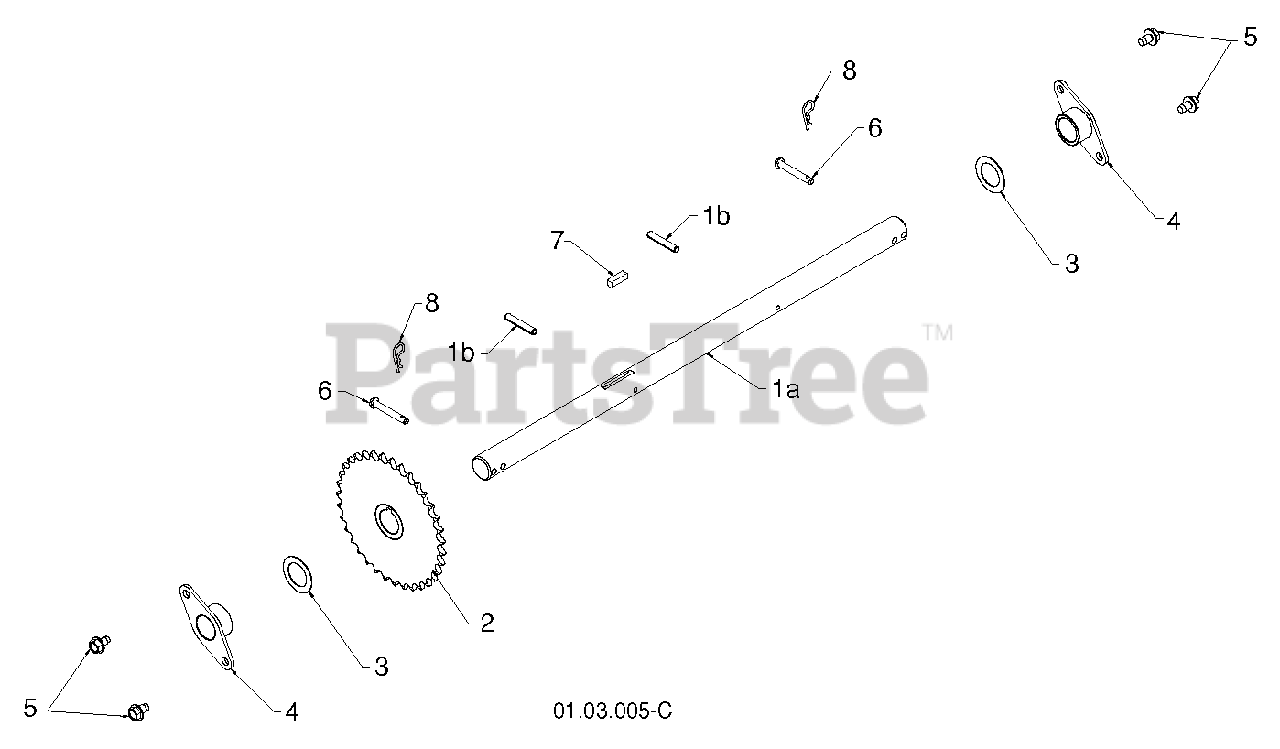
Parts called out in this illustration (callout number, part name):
1	AXLE.SHAFT.ASM.W/ROLPIN.NON-PS
2	SPROCKET.WELDMENT.AXLE.1.00
3	WASHER 1.00
4	BEARING, AXLE
5	SCREW LT
6	RIVET
7	KEY, SQUARE 1/4 X .875
8	RETAINER M
